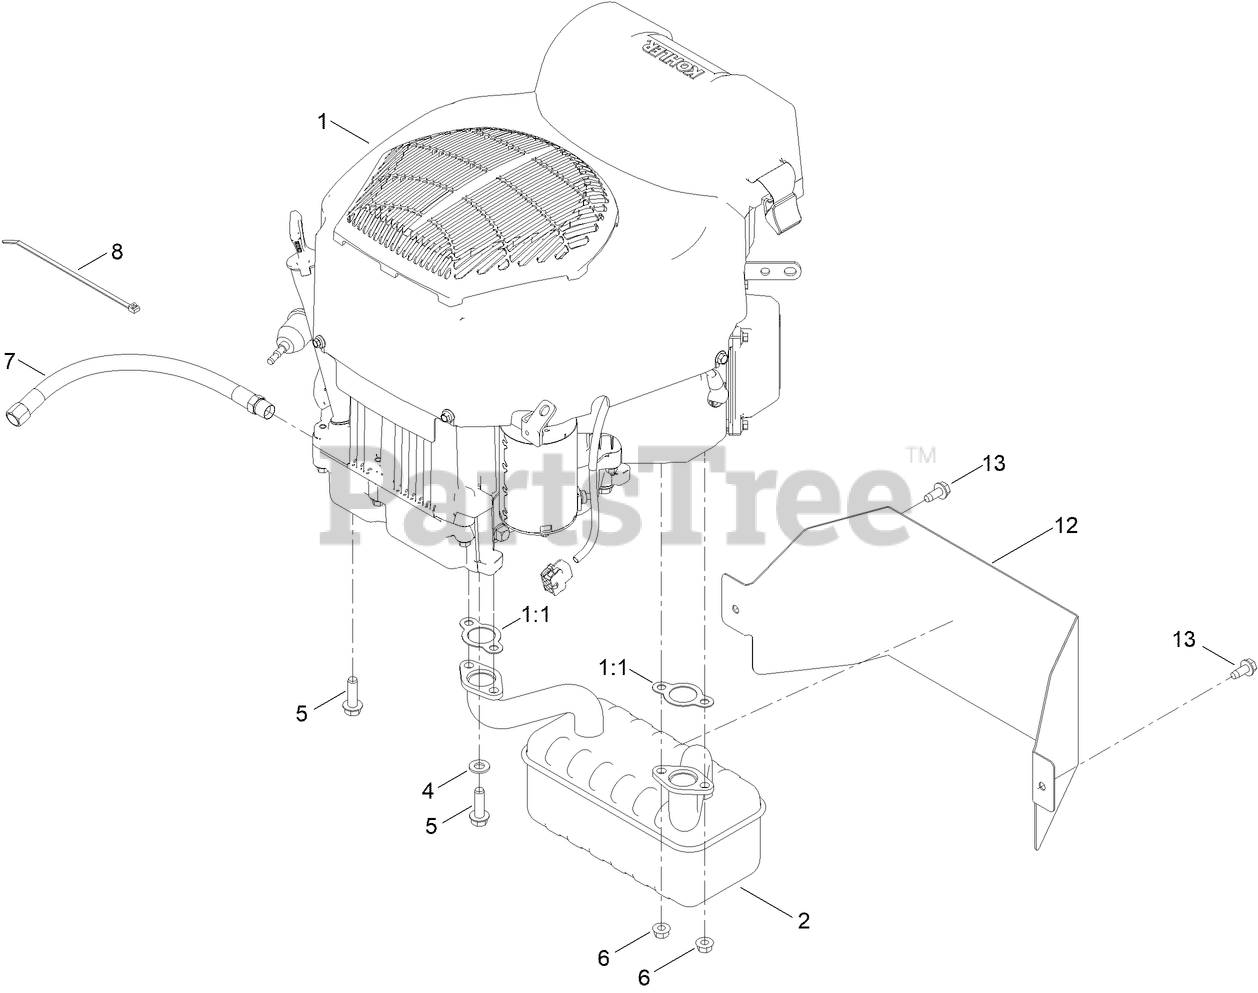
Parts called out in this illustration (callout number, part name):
1:1	GASKET-EXHAUST
2	MUFFLER
4	WASHER-FLAT
5	SCREW-THD
6	NUT-HF
7	HOSE-DRAIN, OIL
8	TIE-CABLE
12	HEAT SHIELD - MUFFLER
13	SCREW-HWHTF
